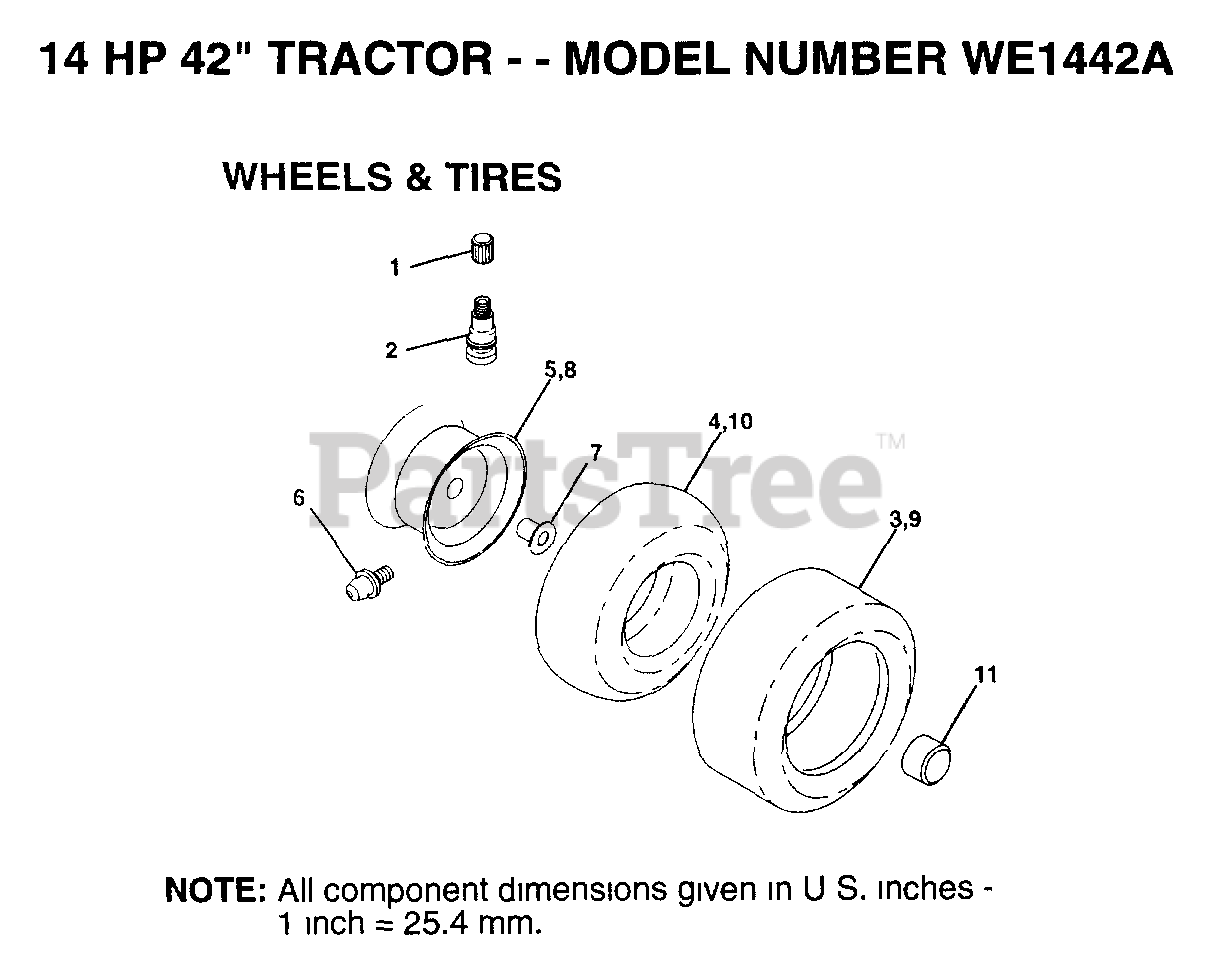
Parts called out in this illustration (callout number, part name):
1	VALVE CAP
2	VALVE STEM LT
4	TUBE.5.3/4.5/6
5	"RIM.ASM.6""FRONT"
6	FITTING LT
7	"FLANGE, BEARING"
8	"RIM.ASM.8""REAR"
10	TUBE.18X9.5-8
11	HUB CAP
